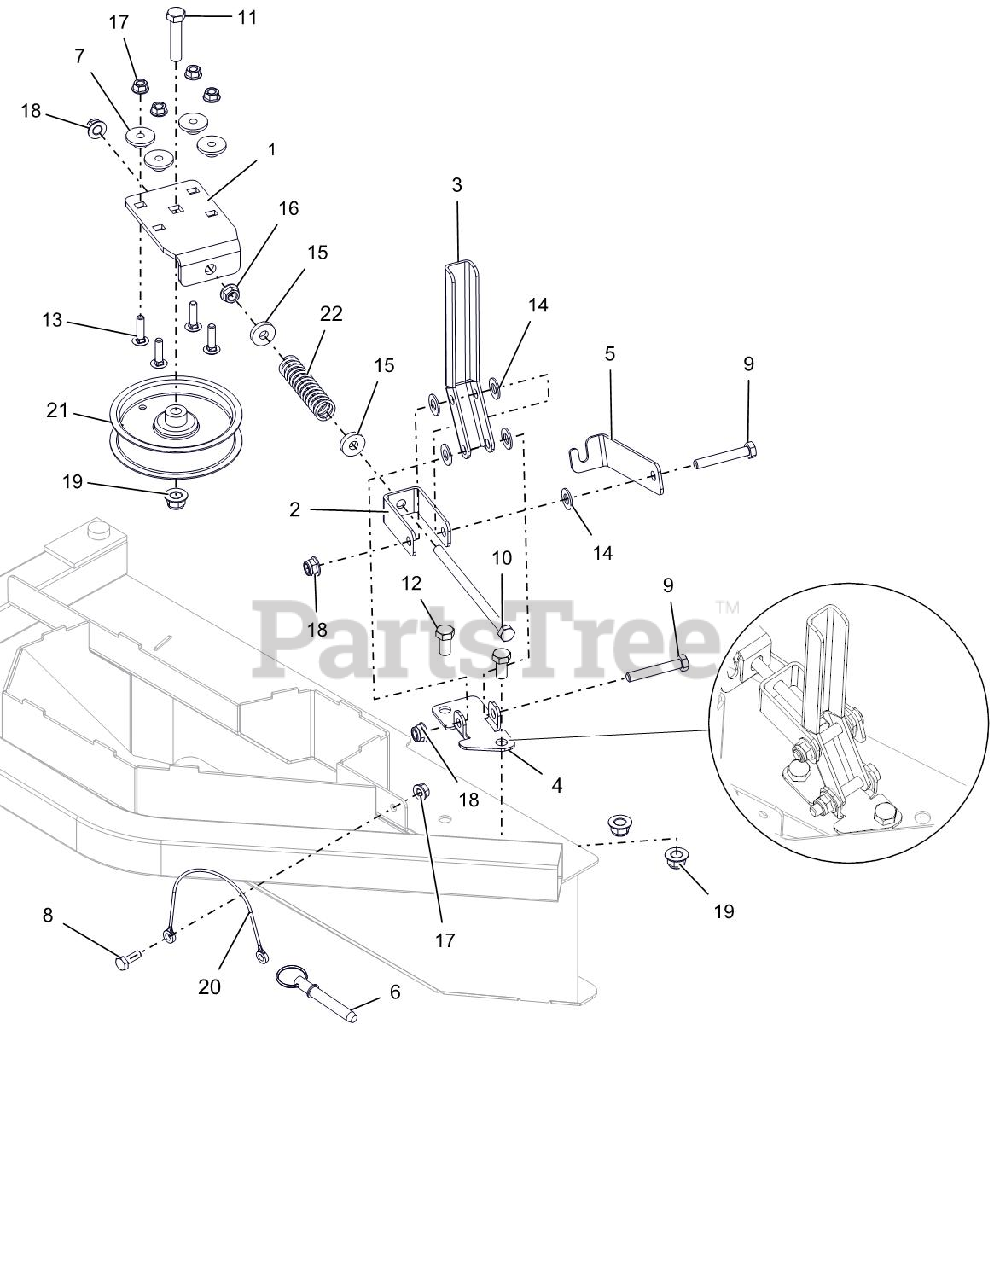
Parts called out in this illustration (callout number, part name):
1	BRACKET, ADJUSTABLE IDLER
2	LINK - IDLER RELEASE
3	LEVER - IDLER RELEASE
4	MOUNT - IDLER RELEASE LEVER
5	LOCK - IDLER RELEASE LEVER
6	PIN, SPRING BALL .375OD X 1.50
7	BSHG-FLG .265X.477X.375X1.00
8	@BLT-HEX .25-20X.75 GR5 YWZC
9	@BLT-HEX .31-18X2.00 GR5 YWZC
10	@BLT-HEX .31-18X5.50 GR5 YWZC
11	@BLT-HEX .38-16X1.75 GR5 YWZC
12	@BLT-HEX .38-16X.75 GR5 YWZC
13	@BLT-RDHDSQNK .25-20X1.00 G5YZ
14	WSHR-FL-NY .375X.75X.060
15	WSHR-FL-STL .328X.87X.179 YWZC
16	NUT-SPNLK-FLG .312-18 YWZC
17	NUT-LK-TOP-FLG .25-20 YWZC
18	@NUT-LK-NYL-FLG .31-18 YWZC
19	@NUT-LK-NYL-FLG .38-16 YWZC
20	CABLE, 12.0 LANYARD, NYLON
21	PULLEY, IDLER 4.00
22	SG-COMP .092X.77X3.13 WLD 36
